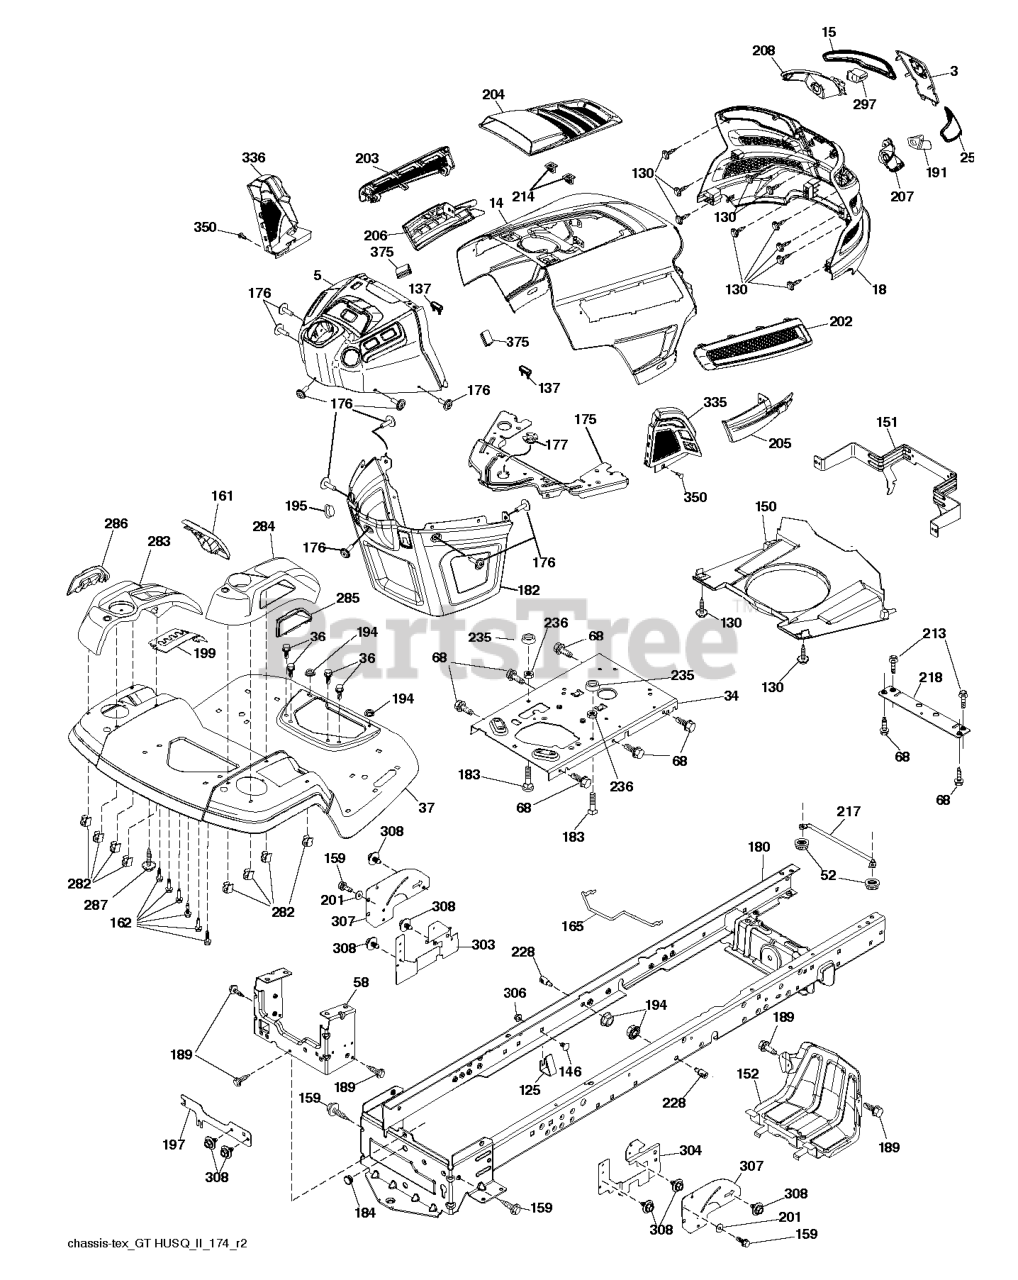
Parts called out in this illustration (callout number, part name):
3	APPLIQUE.SUBASM.GT.HUSQ.II
14	HOOD.ASM.HUSQVARNA.GT.TEX.ORAN
15	LENS.HEADLIGHT.LH.GTII.2011
18	GRILLE SUBASM.GT.II.LOW.HDLGHT
25	LENS.HEADLIGHT.RH.GTII.2011
34	PLATE.ENGINE.WELDED.CHASSIS
36	SCREW 5/16"
37	FENDER.TLT.FS.W/CPH/FW/RSF.668
52	LOCKNUT
58	DRAWBAR UPPER 2PC SMALL FENDER
68	SCR 5/16-18 X 1/2 SELFTAP ZN
125	CLIP.FUEL.LINE
130	SCREW.#10 X 0.750.BOS
137	BUMPER DASH
146	BOLT.RDHD.SHT.SQNK.3/8-16X5/8
150	AIR.DUCT.GTV.BLACK
151	BRACKET.PIVOT.HOOD.GT.HUSQ.II
152	SHIELD.BROWNING.PNT.GT.V2
159	SCREW, 3/8-16X3/4
161	WINDOW.FUEL.LT.HUSQ.TEX.498
162	SCREW.HI-LO.CONSOLE
165	SUPPORT.TANK.REAR.W/TEX
175	PLATE.PNT.CROSSMEMBER.HUSQ/PRE
176	SCREW.#10-24X5/8.RN.QU
177	BUSHING, STEERING
180	CHASS.WLDMNT.TLT.12GA/2PC.20"
182	DASH LOWER.HUSQ.PRED NO CRUISE
183	BOLT.5/16-18X1-1/4 FULL THD
184	PLUG.DEMO.625
189	SCREW
191	INSERT.REFLECTIVE.RH.HUSQ.GTII
194	NUT LOCK HEX FLANGE 5/16-18
195	PLUG.HOLE.DASH.LOWER.12V.BLK
197	SHIELD.DRAWBAR.LT.REAR.TANK
199	PLATE.DECK.LIFT.HUSQ.LT
201	WASHER
202	VENT.SIDE.RH.GT.HUSQ.II.
203	VENT.SIDE.LH.GT.HUSQ.II.498
204	VENT.TOP.HUSQ.GT2
205	SIDE.TRIM.RH.GT.HUSQ.II
206	SIDE.TRIM.LH.GT.HUSQ.II.GRAY
207	HEADLIGHT.CUP.BEZEL.HUS.GT2.RH
208	HEADLIGHT.CUP.BEZEL.HUS.GT2.LH
213	DNB PULLEY-TRANS W/SETSCREWS
214	CLIP.RETAINER.TINNER.
217	ROD.PIVOT.HOOD
218	X-PIECE.HOOD.STOP.NON/
228	STUD.FASTNER.W/ANTI-ROTATE
235	SPACER FENDER
236	NUT.CENTERLOCK.5/16-
282	CLIP.RETAINER.CONSOLE.LT.HUSQ
283	CONSOLE.DECK.LIFT.R.SDFL.HUSQ
284	CONCOLE.CNTRL.PDL.HUSQ.LT.498
285	CONSOLE INSERT RH
286	CONSOLE.INSRT.LH.HUSQ.LT.BLACK
287	SCREW 1/4X20
297	INSERT.REFLECTIVE.LH.HUSQ.GTII
303	SHIELD.LWR.LH.LTGT.NON30
304	SHIELD.LWR.RH.LTGT.NON30.NOTCH
306	NUT LOCK FLG 3/8-16 UNC
307	SHIELD.UPPER.LT.GT.ISO
308	BOLT.5/16-18UNCX3/4 W/SEMS.BLK
335	COVER.LOWER.DASH.RH.BLACK
336	COVER-LH.LOWER.DASH.GT2.BLACK
350	CLIP.X-MAS.TREE
375	BUMPER CLIP-ON. DASH 1"
